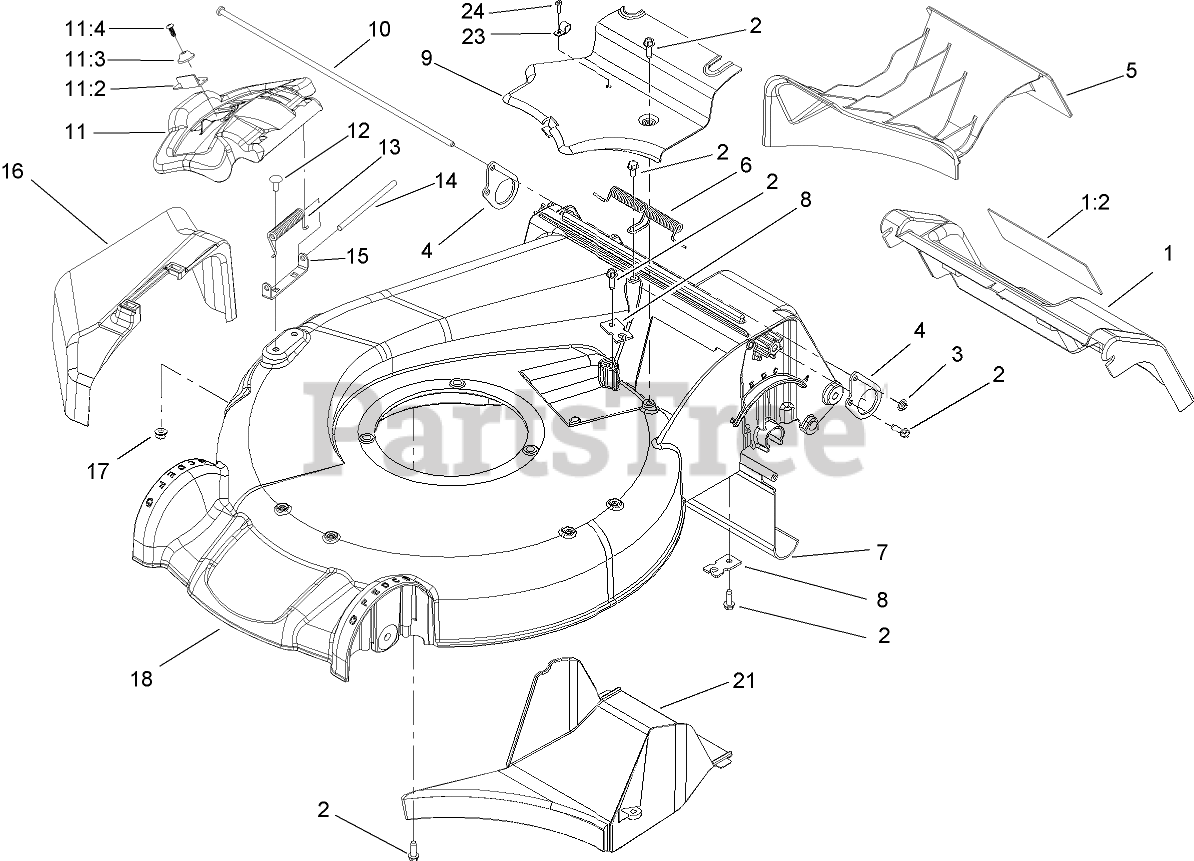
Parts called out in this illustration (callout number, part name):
1	REAR DOOR ASM
1:2	DECAL-WARNING
2	SCREW-HWHTF
3	NUT-SPEED
4	PLATE-SUPPORT, DOOR
5	MULCH PLUG ASM
6	Spring-Door, Rear
7	SHIELD-TRAILING
8	BRACKET-CABLE, TRACTION
9	COVER-BELT
10	ROD-SUPPORT, DOOR
11	DISCHARGE DOOR ASM
11:2	LATCH-DOOR
11:3	CAP-DOOR
11:4	SCREW-PLASTITE
12	SCREW-CARR
13	SPRING-TORSION
14	ROD-COVER
15	BRACKET-COVER
16	CHUTE-DISCHARGE, SIDE
17	NUT-HHF
18	HOUSING ASM
21	TUNNEL-DISCHARGE
23	CLAMP
